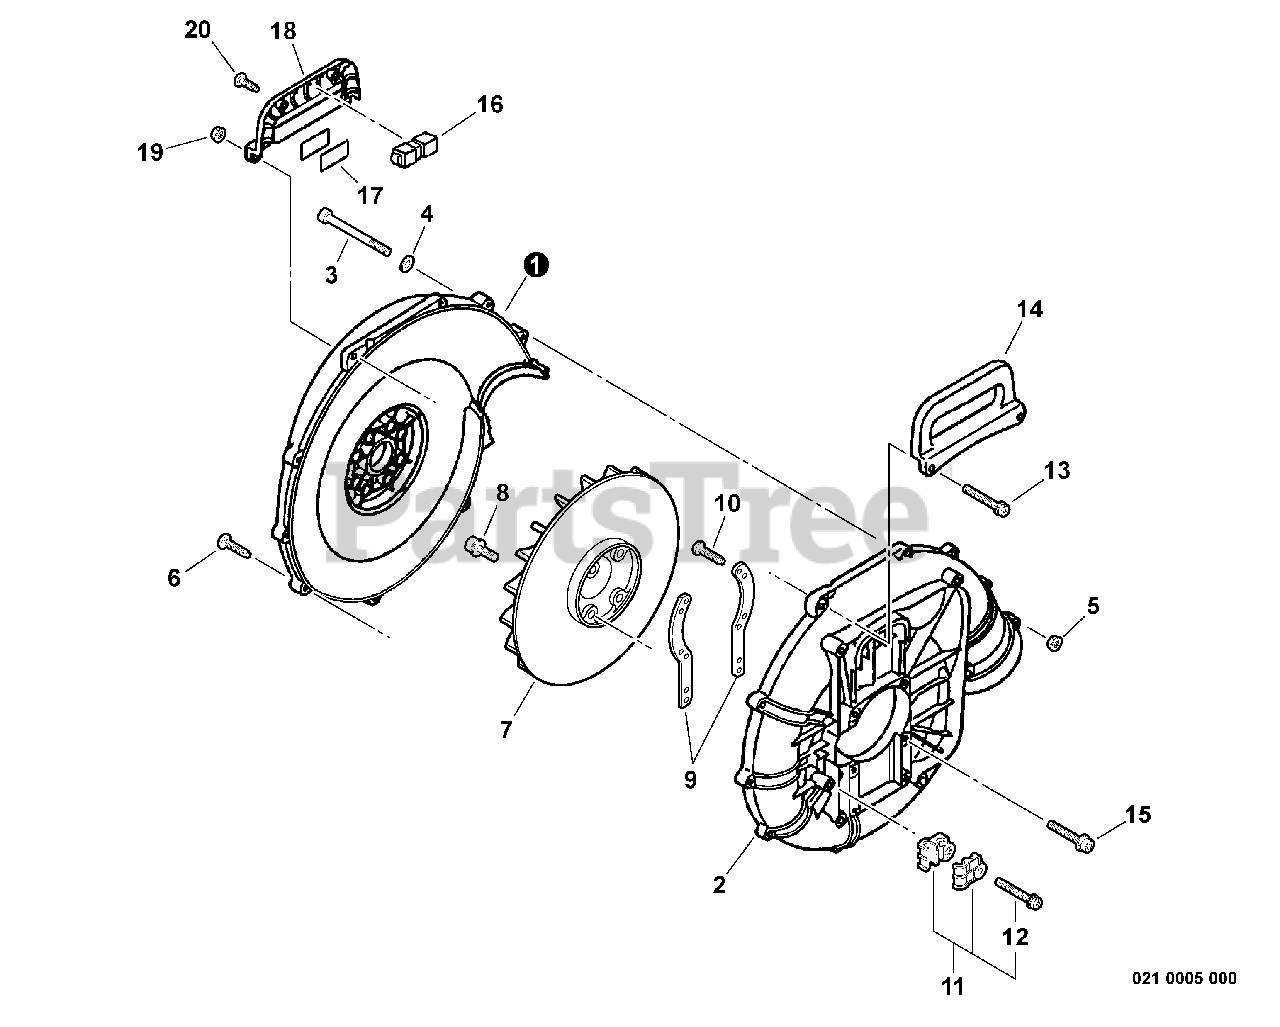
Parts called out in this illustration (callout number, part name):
1	COVER, FAN - INNER
1	CASE, FAN
2	COVER, FAN - OUTER
2	CASE, FAN
3	BOLT 5×60
4	WASHER, FLAT 5.5×10×0.8
5	NUT, FLANGE M5
6	SCREW 5×30
7	FAN
8	BOLT 5×20
9	BRACKET, ENGINE
10	SCREW TAPPING 3×12
11	CABLE HOLDER KIT
12	SCREW 5×25
13	SCREW 5×45
14	HANDLE
15	SCREW 5×32
18	HANDLE
18	HANDLE, REAR
19	NUT, FLANGE M5
20	SCREW 5×16
